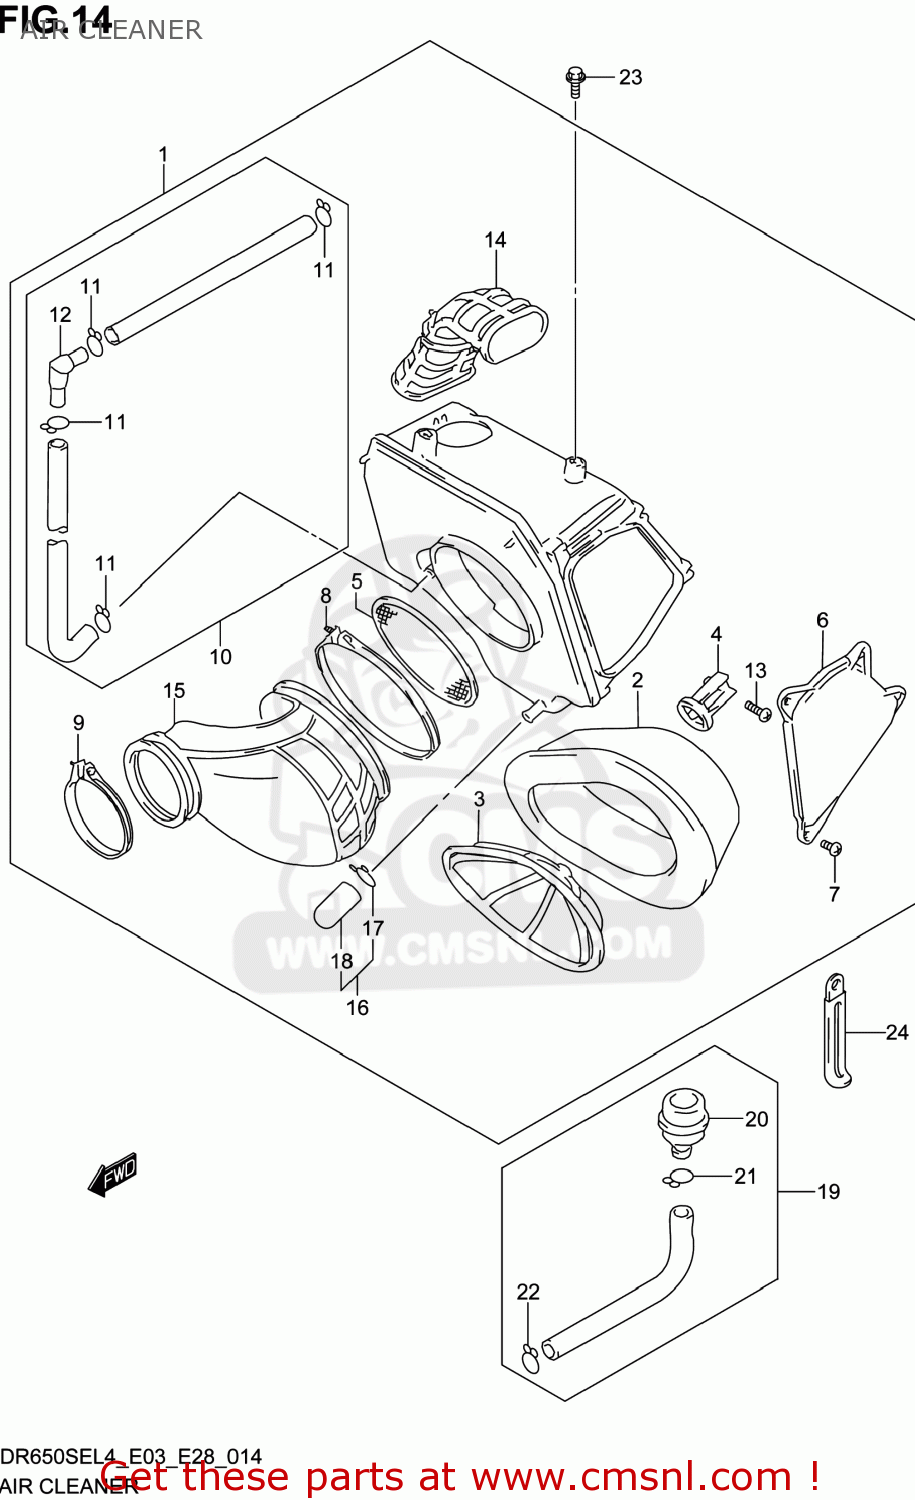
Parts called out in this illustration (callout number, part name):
1	CLEANER ASSY,AIR
2	FILTER
3	HOLDER,FILTER
4	STOPPER,HOLDER
5	TRAP,FRAME
6	CAP,CLEANER
7	SCREW
8	CLAMP,OUTLET TUBE
9	CLAMP
10	TUBE ASSY,BREATHER
11	CLIP
12	JOINT
13	SCREW
14	TUBE,INLET
15	TUBE,OUTLET
16	PLUG ASSY,DRAIN
17	CLIP
18	PLUG
19	CLEANER ASSY,AIR NO.2
20	FILTER,2ND AIR CLEANER
21	CLIP
22	CLIP
23	BOLT
24	CLAMP(L:80)
